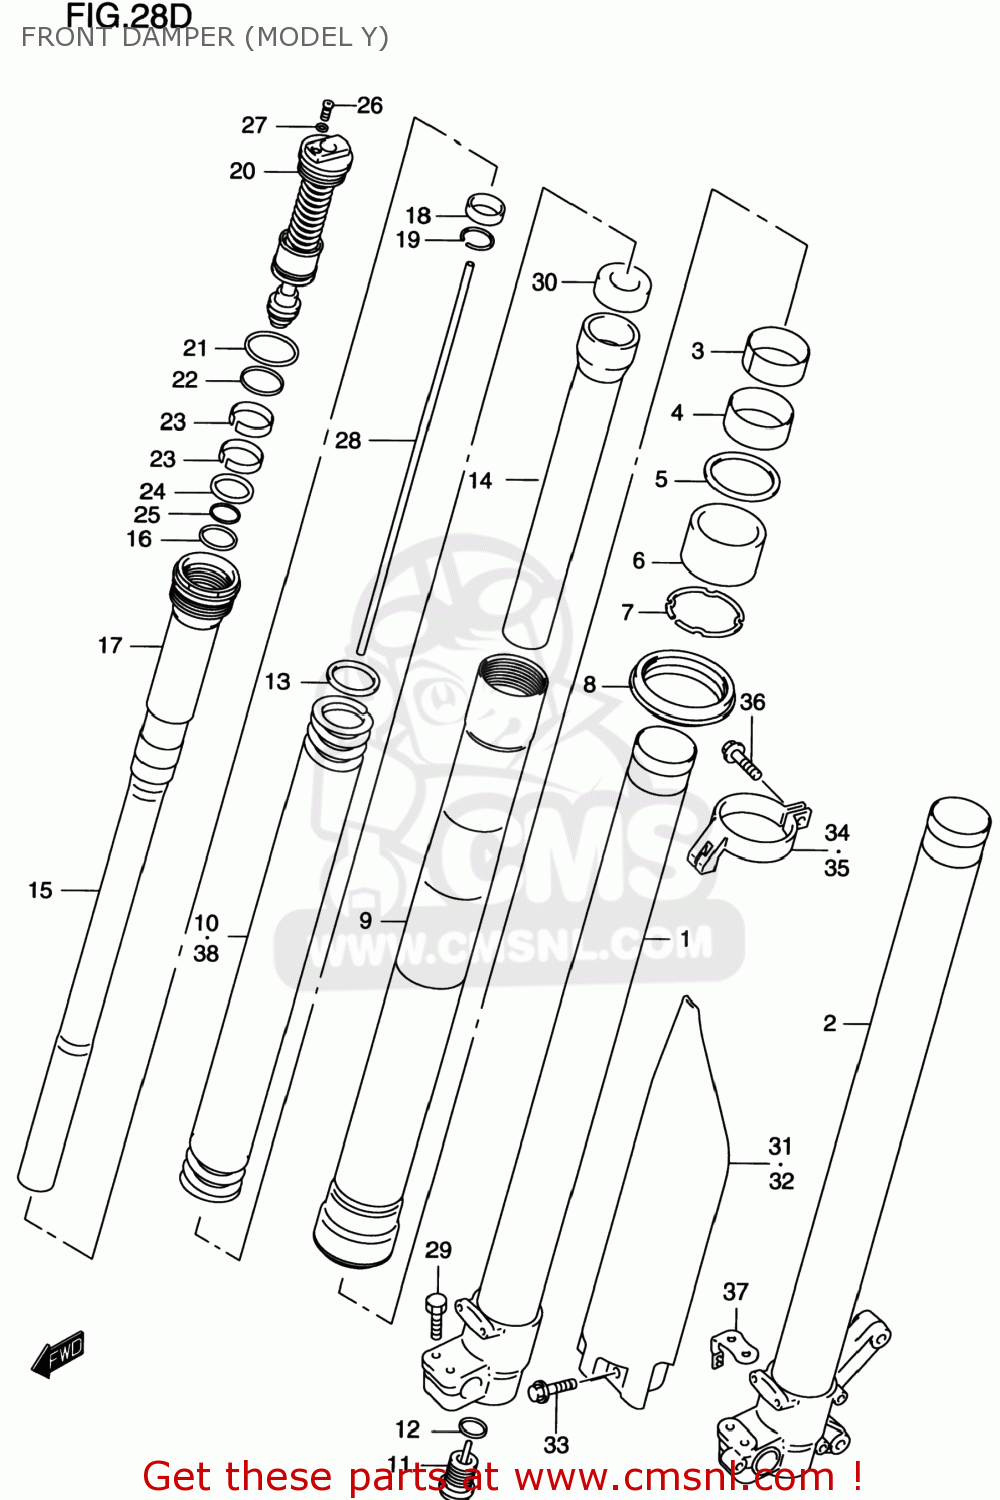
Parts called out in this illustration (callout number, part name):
1	TUBE,INNER,R
2	TUBE,INNER,LEFT
3	BUSH,SLIDE
4	BUSH,GUIDE
5	SPACER,SEAL
6	SEAL,OIL
7	RING,STOPPER
8	SEAL,DUST
9	TUBE,OUTER
10	SPRING,FR(K=0.42)
11	BOLT,CTR
12	O RING
13	STOPPER,SPRING
14	COLLAR,SPRING
15	ROD,DAMPER
16	O-RING
17	TANK,SUB
18	VALVE,OIL LOCK
19	RING,STOPPER
20	BOLT,FORK
21	O RING
22	O RING
23	BUSH,FORK BOLT SLIDE
24	O RING
25	O RING,LWR
26	BOLT,PLUG
27	O RING,PLUG
28	ROD,PUSH
29	BOLT,HANDLE HOLDER(8X35)
30	SEAT,SPRING
31	PROTECTOR,FR FORK,R
32	PROTECTOR,FR FORK,L
33	BOLT,PROTECTOR(6X10)
34	GUIDE,PROTECTOR,R
35	GUIDE,PROTECTOR,L
36	BOLT
37	STOPPER,BRAKE HOSE,L
38	SPRING,FR(K=0.38)
